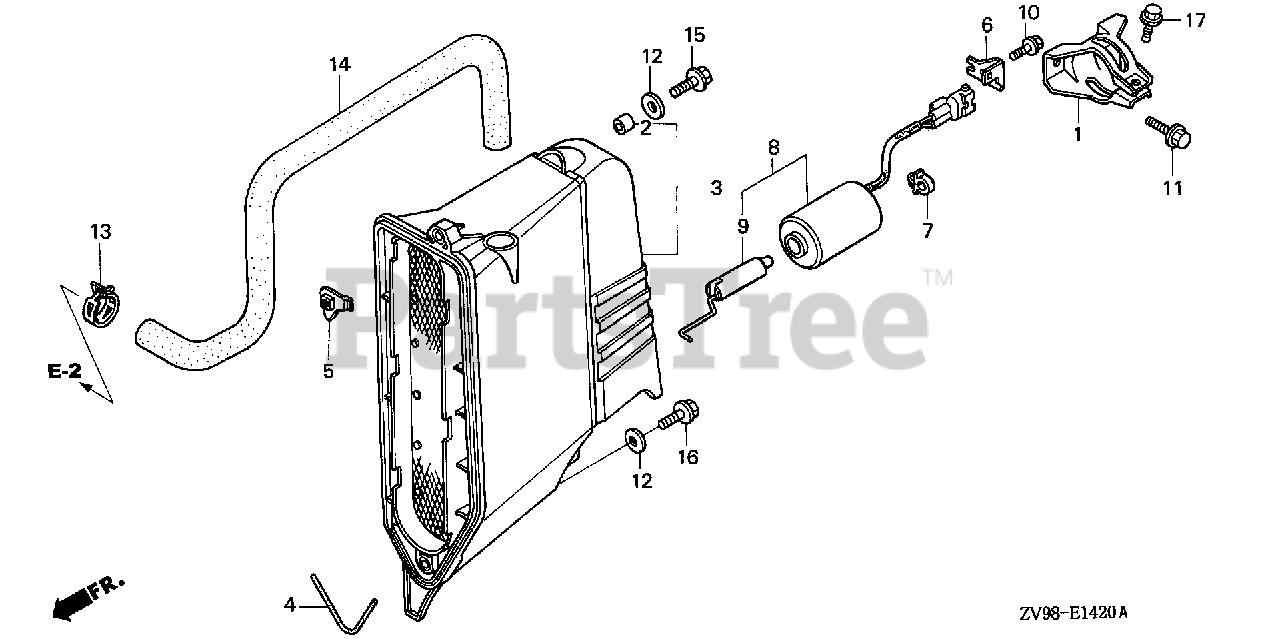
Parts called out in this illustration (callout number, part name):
1	STAY, SOLENOID
2	COLLAR, DISTANCE
3	COVER, MUFFLER
4	GASKET, MUFFLER COVER
5	NUT, MUFFLER COVER
6	BRACKET, CONNECTOR
7	HOLDER, STOP SWITCH WIRE
8	SOLENOID ASSY., REMOTE CHOKE
9	PLUNGER, SOLENOID
10	BOLT, FLANGE (6X12)
11	BOLT, FLANGE (6X14) (CT200)
12	WASHER (6.5X18)
13	CLAMP, TUBE (D17)
14	TUBE, BREATHER
15	BOLT, FLANGE (6X25)
16	BOLT, FLANGE (6X40)
17	BOLT, FLANGE (6X12)
